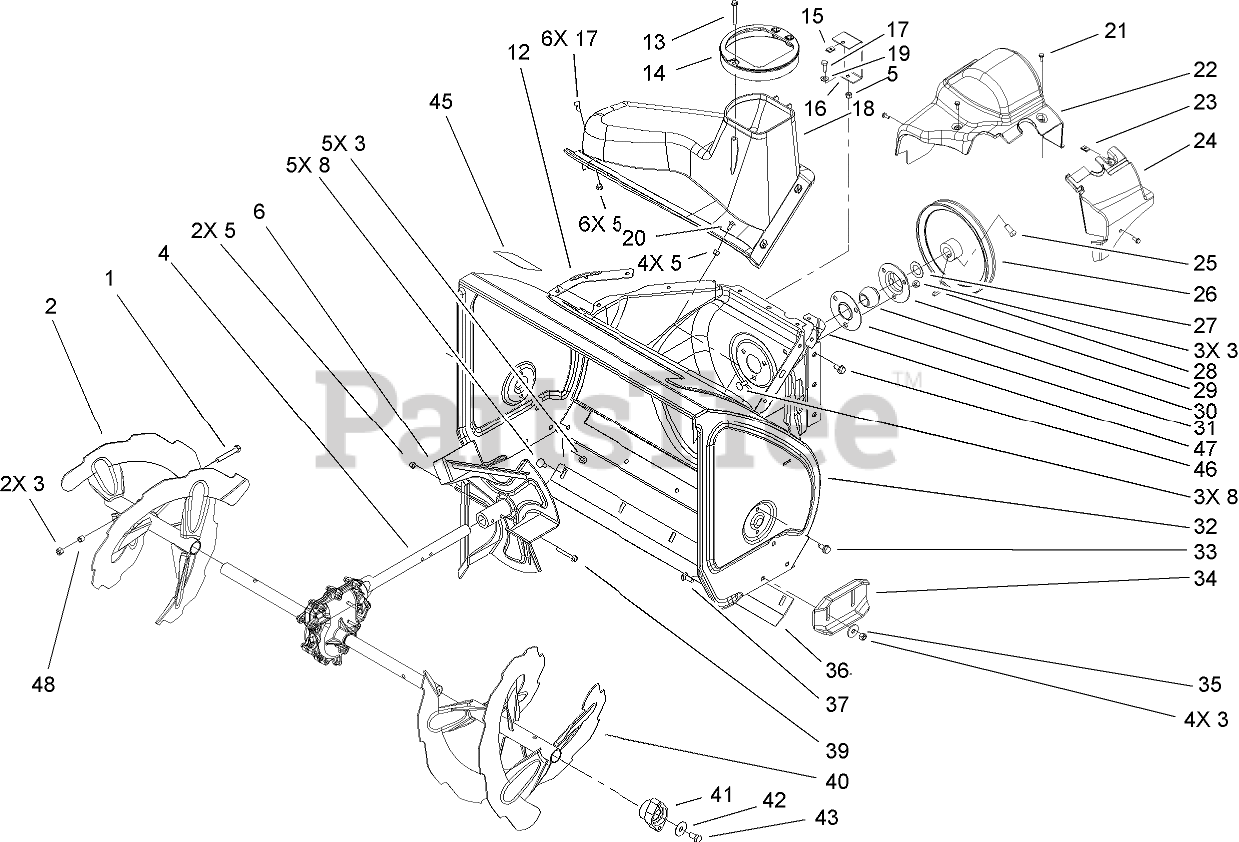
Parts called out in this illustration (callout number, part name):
1	SCREW-HH
2	RH AUGER ASM
3	NUT-LOCK, NI
4	28 INCH AUGER GEARCASE ASM
5	NUT-LOCK, NI
6	IMPELLER ASM
8	SCREW-CARR
12	SEAL-FLANGE, COVER
13	SCREW-PLASTITE
14	GUIDE-CHUTE
15	NUT-SPEED, U-TYPE
16	BRACKET-COVER, CLIP NUT
17	SCREW-HH
19	WASHER-FLAT
20	BOLT-CARR
21	SCREW-HWH
22	COVER-BELT
23	NUT-SPEED
24	COVER-EXTENSION, BELT
25	SCREW-SET, SQH
26	PULLEY-IMPELLER
27	WASHER-THRUST
28	KEY-WOODRUFF
29	FLANGE-CUP, BEARING
30	BEARING-BALL
31	FLANGE-CUP, BEARING
32	HOUSING-AUGER, 28 INCH
33	SCREW-HWHTF
35	WASHER
36	SCRAPER-FIXED
37	SCREW-CARR
39	SCREW-HHF
40	LH AUGER ASM
41	BEARING-AUGER
42	WASHER
43	SCREW-HH
45	DECAL-WARNING, AUGER
46	SCREW-HWHTF
48	SPACER
